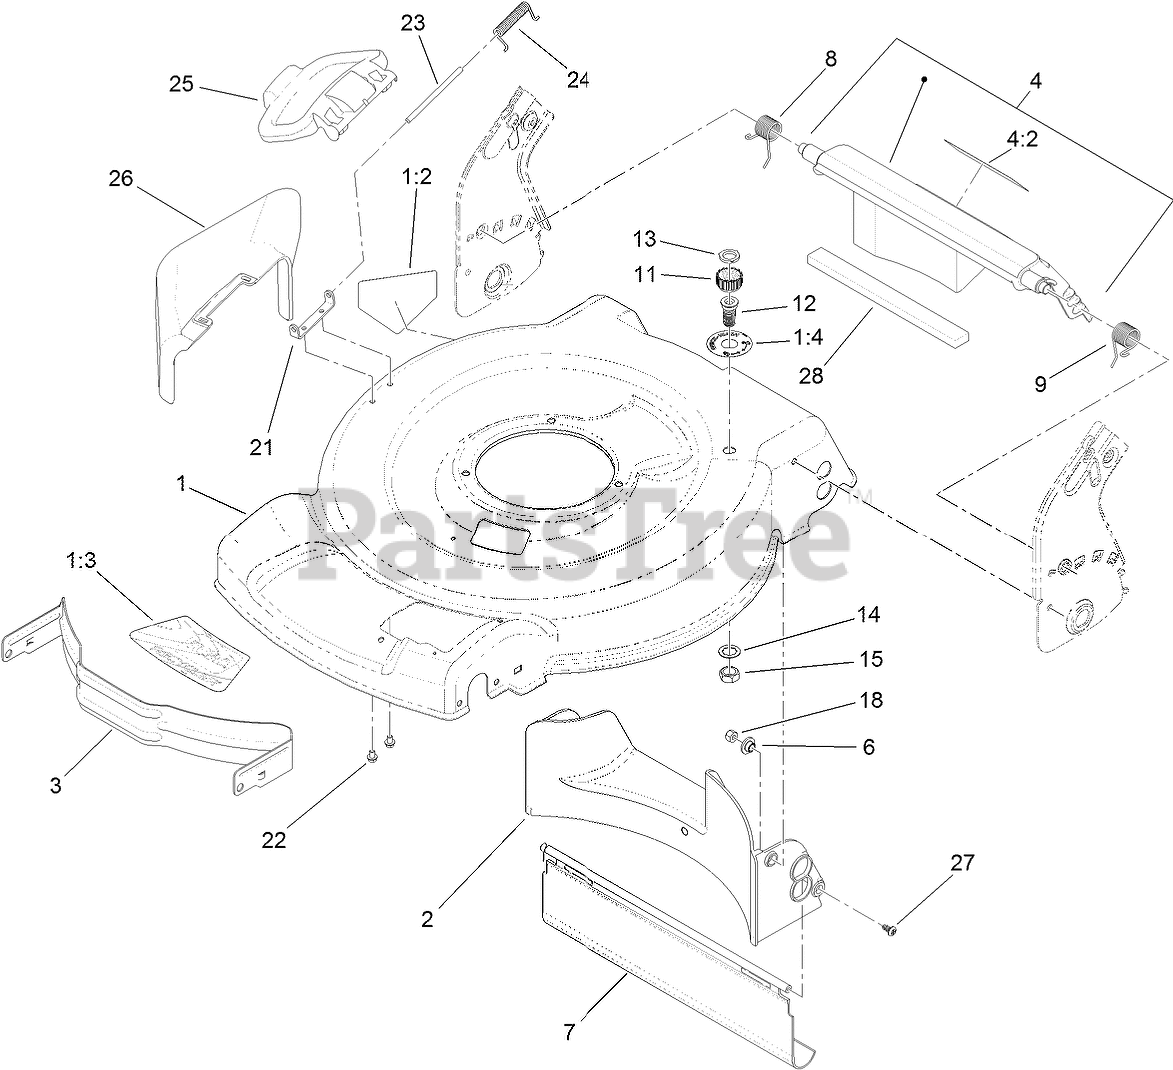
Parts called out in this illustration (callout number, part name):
1	HOUSING ASM
1:2	DECAL-DANGER
1:3	DECAL-RECYCLER
1:4	DECAL-PORT, WASHOUT
2	BAFFLE-REAR
3	BAFFLE-FRONT
4	REAR DEFLECTOR ASM
4:2	DECAL-WARNING
6	WASHER-STEPPED, BAFFLE
7	SHIELD-TRAILING
8	SPRING-TORSION
9	SPRING-TORSION
11	COUPLING-HOSE, WASHOUT PORT
12	PORT-WASHOUT
13	WASHER-SEAL, WASHOUT PORT
14	WASHER-TOOTH, INTERNAL
15	NUT-JAM
18	NUT-LOCK, NI
21	BRACKET-COVER
22	SCREW-HWH
23	ROD-COVER
24	SPRING-TORSION
25	DEFLECTOR-SIDE
26	CHUTE-DISCHARGE, SIDE
27	SCREW-PTH
28	FOAM-SEAL
